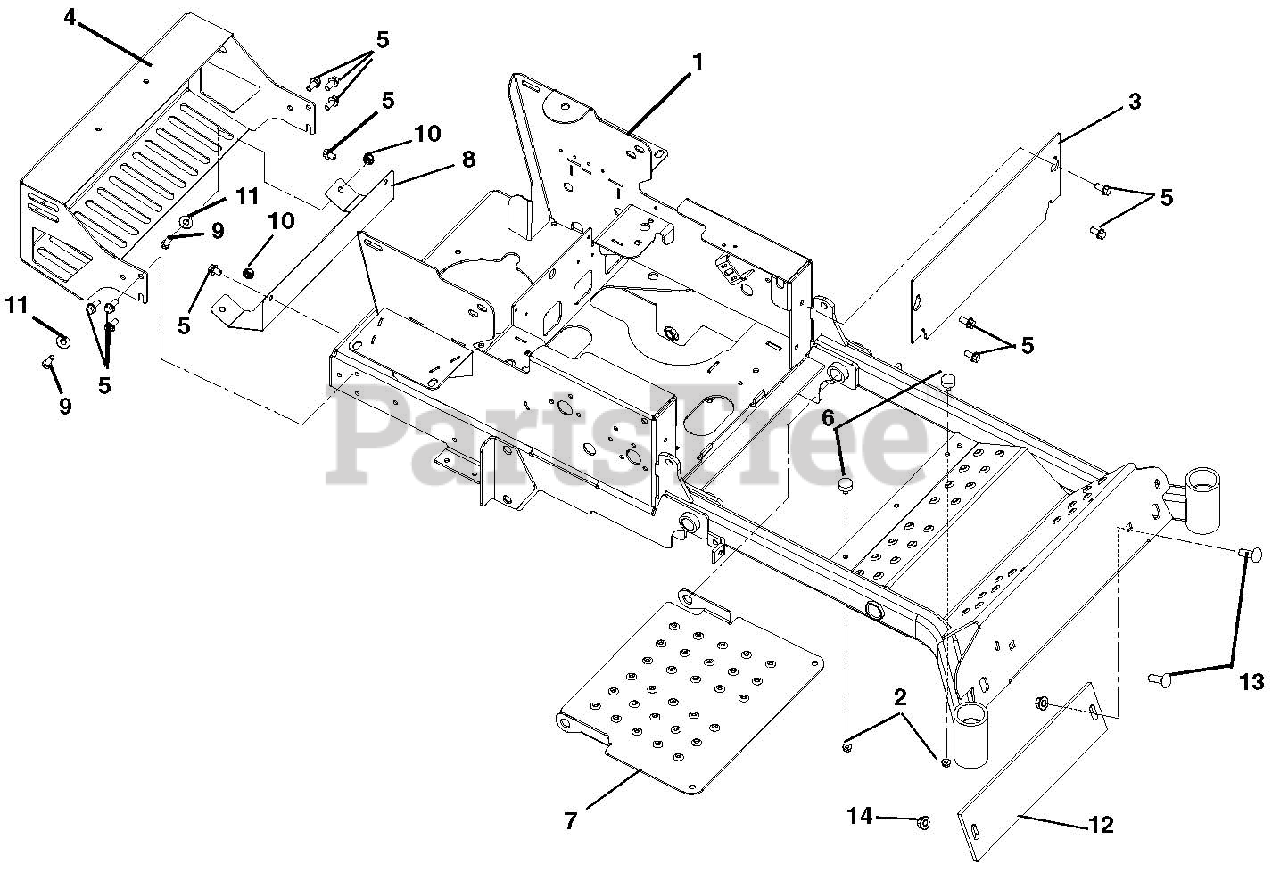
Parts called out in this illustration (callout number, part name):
1	52-60" Main Frame
1	44-48" Main Frame Weldment
2	Nut, Spin Lock Flange .312-18
3	Kick Plate
4	Weldment Gravely, CZ Bumper
5	Screw, Tapping .38-16 x .75 Hex Washer Head
6	Bumper, Rubber
7	Panel, Inspection
8	Heat Shield
9	Bolt, Hex .38-16 x 1.00 Grade 5
10	Nut, Nyloc Flange .38-16
11	Washer, Flat Steel .438 x 1.00 x .083
12	Counterwieght CZ Front- Red
13	Bolt, Round Head Square Neck .50-13 x 1.75 Grade 5
14	Nut .50-13 Nyloc Flange
